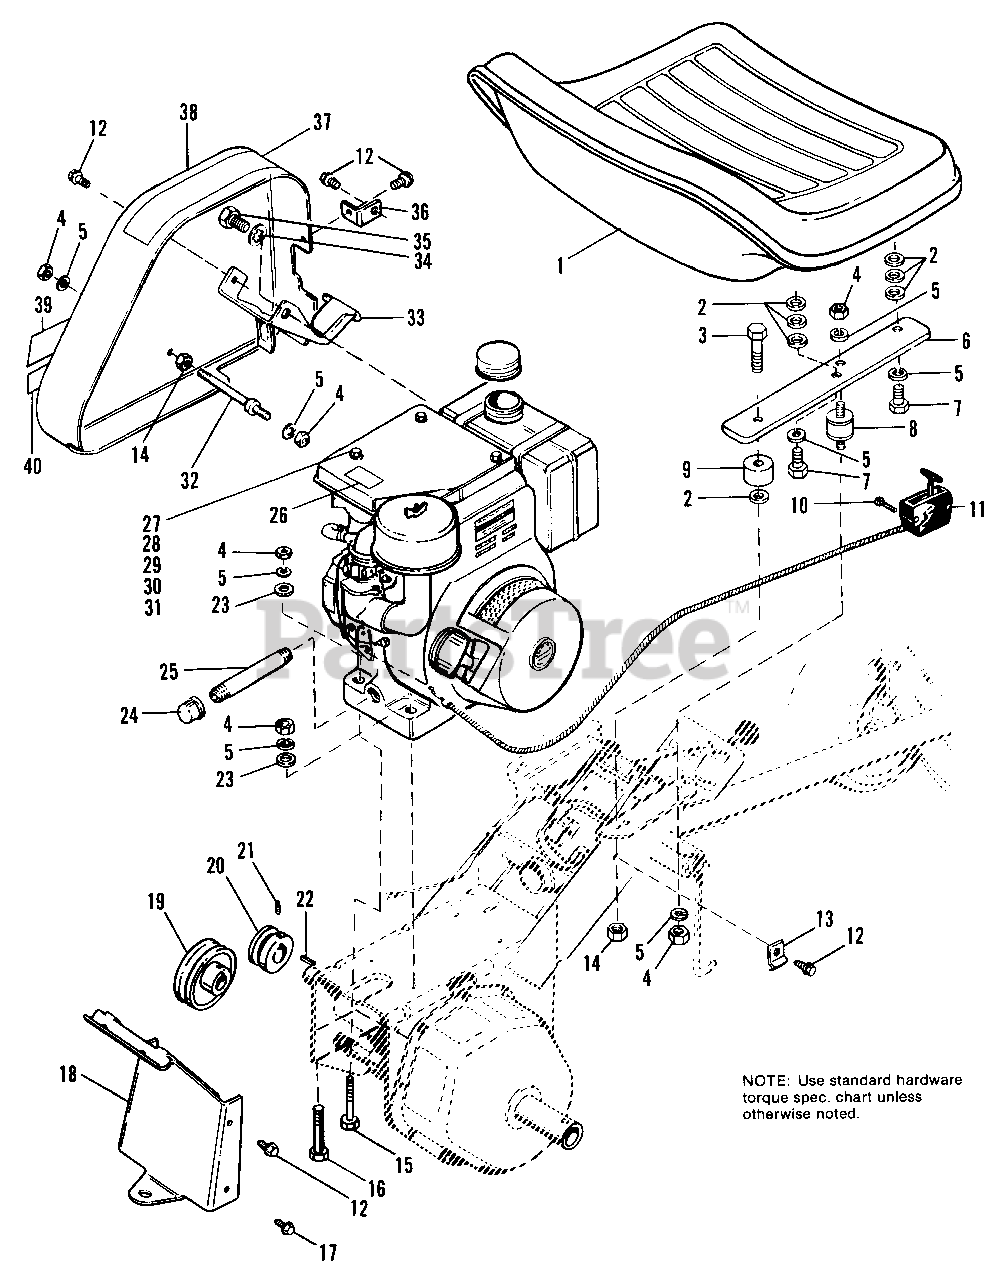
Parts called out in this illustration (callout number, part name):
1	SEAT ASSY.
2	WASHER, Plain, 5/16
3	CASPCREW, Hex Hd., 5/16-18 x 1-1/2
4	NUT, Hex, Full, 5/16-18
5	LOCKWASHER, 5/16
6	SUPPORT, Seat
7	CAPSCREW, Hex Hd., 5/16-18 x 1
8	CONNECTOR, Cushion
9	MOUNT, Rubber
10	SCREW, Hex, Washer Hd., #10-24 x 1
11	THROTTLE & CHOKE ASSY.
12	SCREW, Tapping, 5/16-18 x 1/2
14	LOCKNUT, Hex, 5/16-18
15	SCREW, Hex, Special
16	CAPSCREW, Hex Hd., 5/16-18 x 1-3/4
17	SCREW, Tapping, 1/4-20 x 1/2
18	PLATE, Hitch, Rear
19	PULLEY, Drive, Transmission
20	PULLEY, Engine
21	SETSCREW, 5/16-18 x 5/16
22	KEY, 1/4 x 1/4 x 2-1/4
23	WASHER, Plain, 5/16
24	CAP, Pipe, 3/8
25	NIPPLE, Pipe
26	DECAL, Caution
27	CAPSCREW, Hex Hd., 1/4-20 x 1-3/4
28	SCREW, Taptite, Hex, 1/4-20 x 3/8
29	SHIELD, Heat
30	SUPPORT, Heat Shield
33	STOP, Belt
34	LOCKWASHER, Int., 1/2
35	CAPSCREW, Hex Hd., 1/2-20 x 1
36	BRACKET, Pulley Guard
37	DECAL, Safety
38	GUARD, Pulley
39	DECAL, Cover
40	DECAL, 3008
